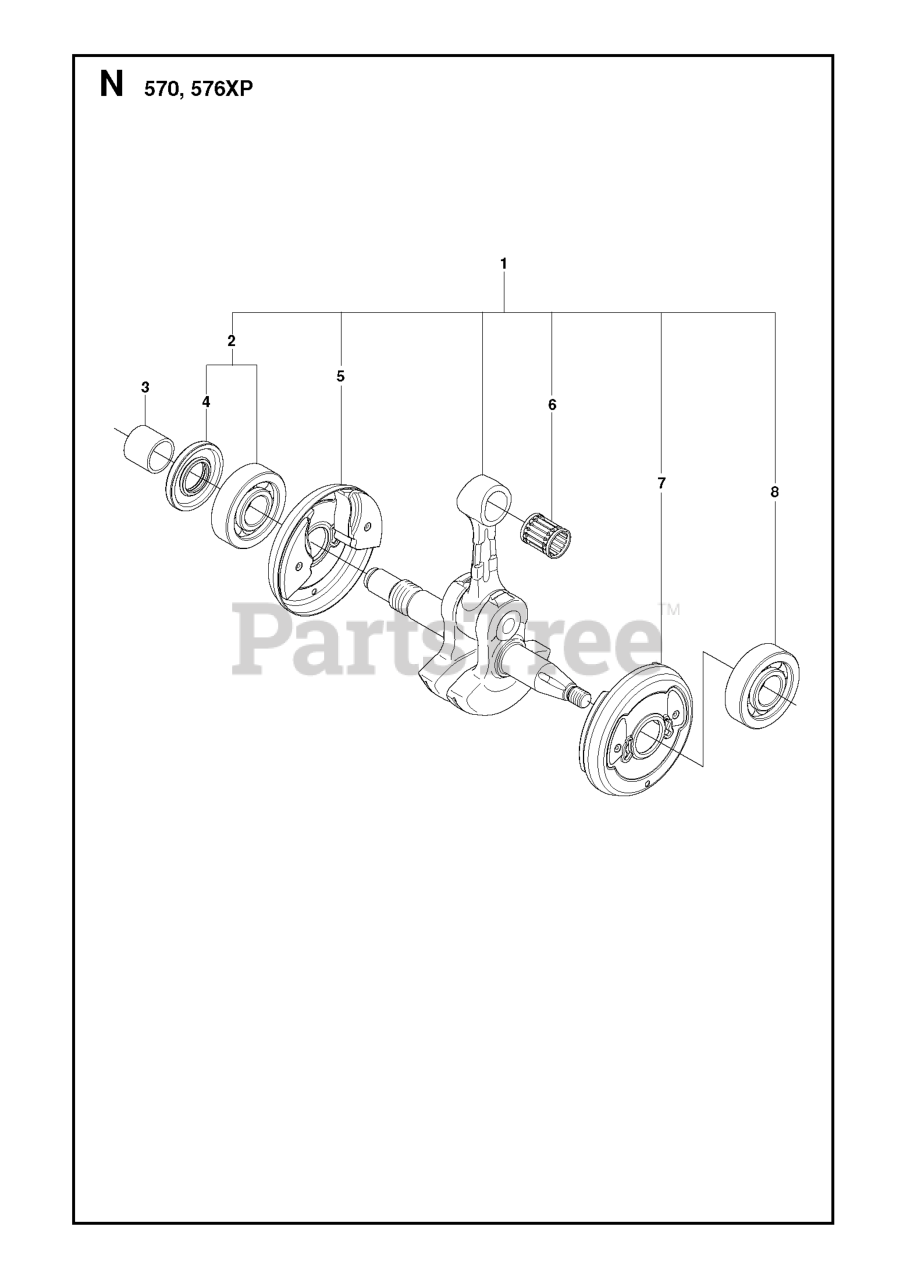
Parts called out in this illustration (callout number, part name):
1	CRANKSHAFT
1	RP CRANKSHAFT ASSY
2	%BALL BEARING
4	RADIAL SEAL
6	SUPPORT BUSHING
8	%BALL BEARING
8	BALL BEARING-6202-C3 SKF
